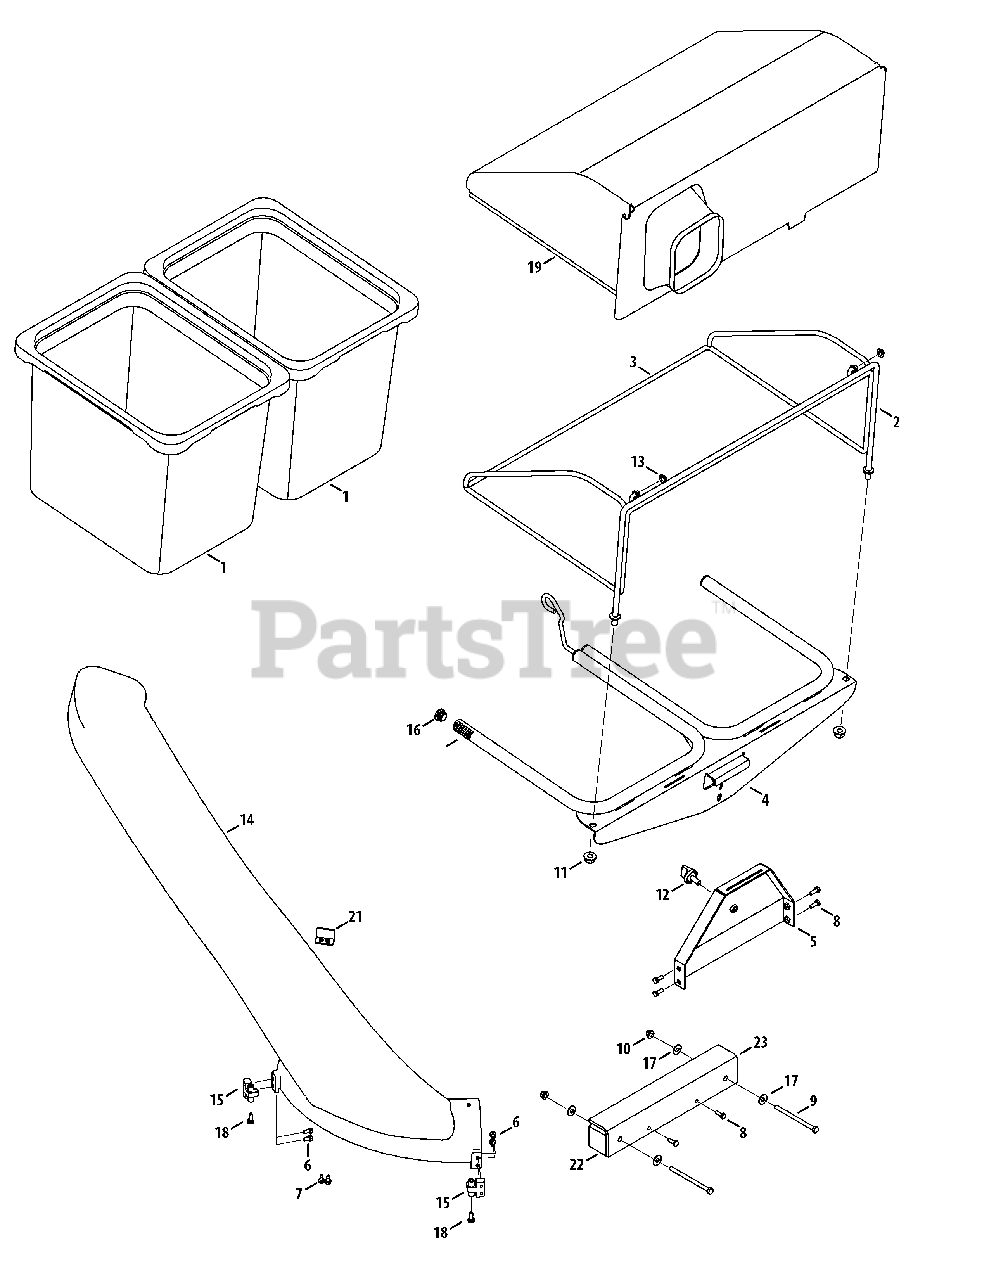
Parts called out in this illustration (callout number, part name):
1	Grass Bag
6	Hex Lock Screw, 1/4-15, 050
7	Tap Screw, 1/4-20, 0500
8	Hex Head Screw, 1/4-20, 75
9	Hex Head Screw, 5/16-18, 450
10	Flange Lock Nut, 5/16-18
11	Flange Lock Nut, 1/2-13
12	Knob, 3/8-16, 875
13	Push Cap, 3/8 ROD
14	Chute Tube
15	Chute Mount Bracket
16	Plug End
17	Flat Washer, 349 x 879 x 063
18	Shoulder Screw, 1/4-15, 750
19	Grass Catcher Hood
21	Boot Switch Safety Bracket
22	Weight Bar
23	Weight Bar Mounting Bracket
